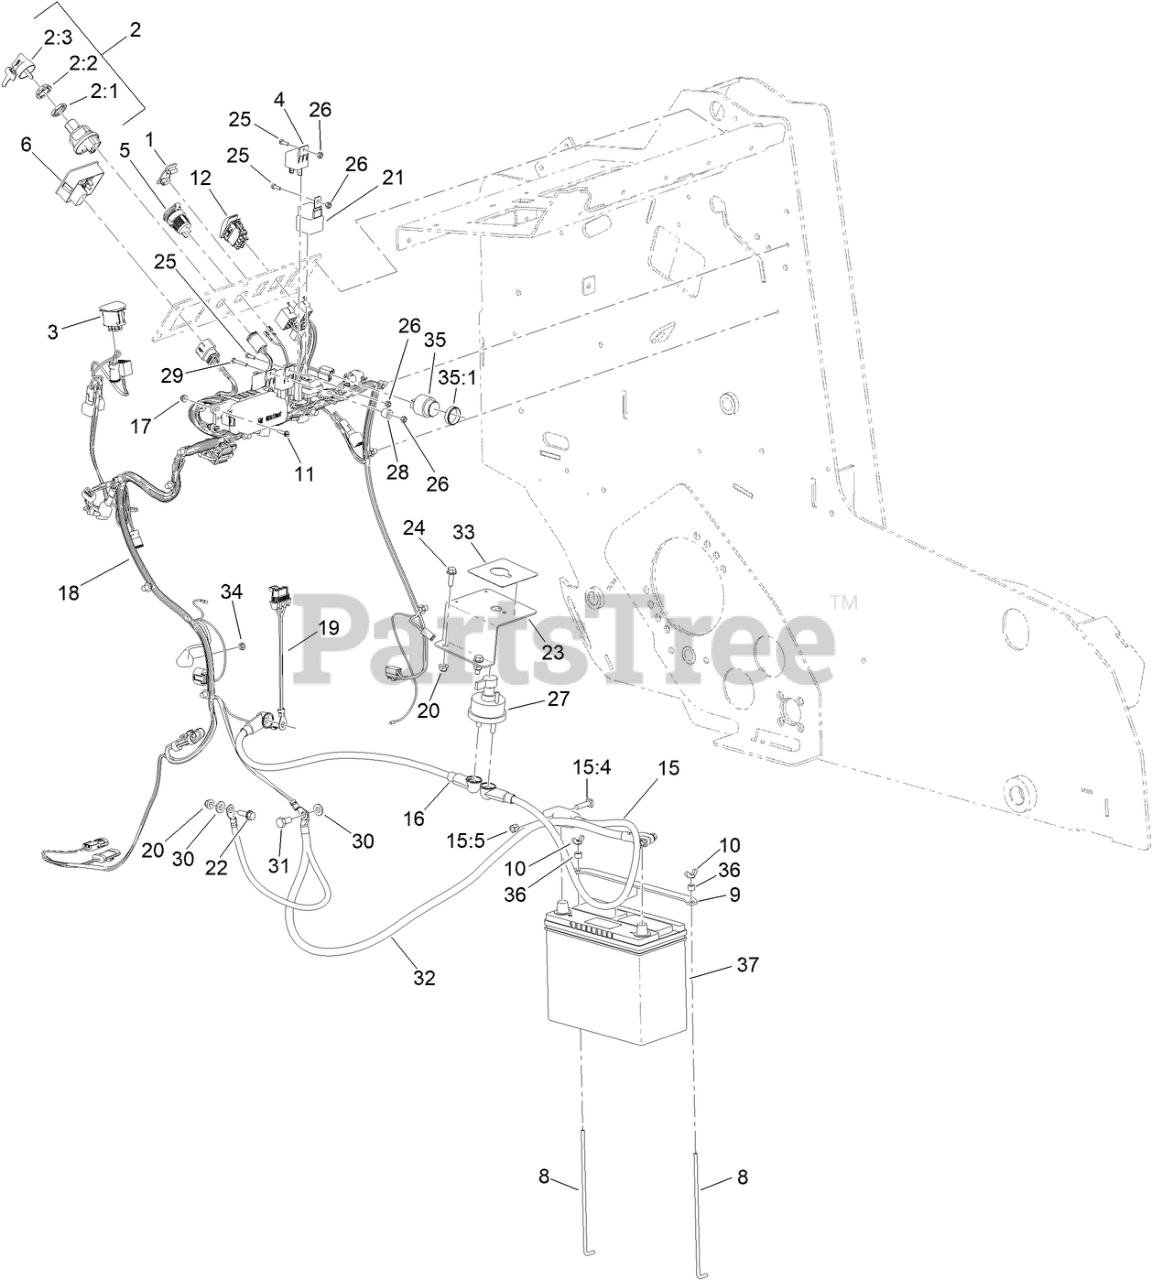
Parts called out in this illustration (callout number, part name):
1	PLUG-HOLE
2	IGNITION SWITCH ASM
2:1	NUT-HEX
2:2	NUT-FACE, M22 (PLASTIC)
2:3	SET-KEY, IGNITION
3	SWITCH
4	RELAY
5	RECEPTACLE-12V
6	MODULE-HOUR METER
8	ROD-HOLD DOWN, BATTERY
9	STRAP-HOLD DOWN, BATTERY
10	NUT-WING
11	SCREW-HWH
12	SWITCH
15	CABLE-BATTERY, RD ASM
15:4	BOLT-BATTERY CLAMP, 5/16-18 UNC
15:5	NUT-CLAMP, BATTERY
16	CABLE-BATTERY, RD ASM
17	NUT-HF
18	HARNESS-WIRE, TX700
19	HARNESS-WIRE, FUSIBLE LINK
20	NUT-HF, NI
21	RELAY-MINI
22	SCREW-HHF
23	SWITCH BRACKET
24	SCREW-HHF
26	NUT-LOCK, NI
27	SWITCH-DISCONNECT, MASTER
28	SPACER - FUEL TANK
29	SCREW-HH
30	WASHER-HARDENED
31	SCREW-HH
32	CABLE-BATTERY, BK ASM
33	DECAL-BATTERY DISCONNECT
34	NUT-HF
35	AUDIO ALARM ASM
35:1	NUT-PLASTIC, KNURLED
36	SPACER
37	BATTERY - CORROSIVE
